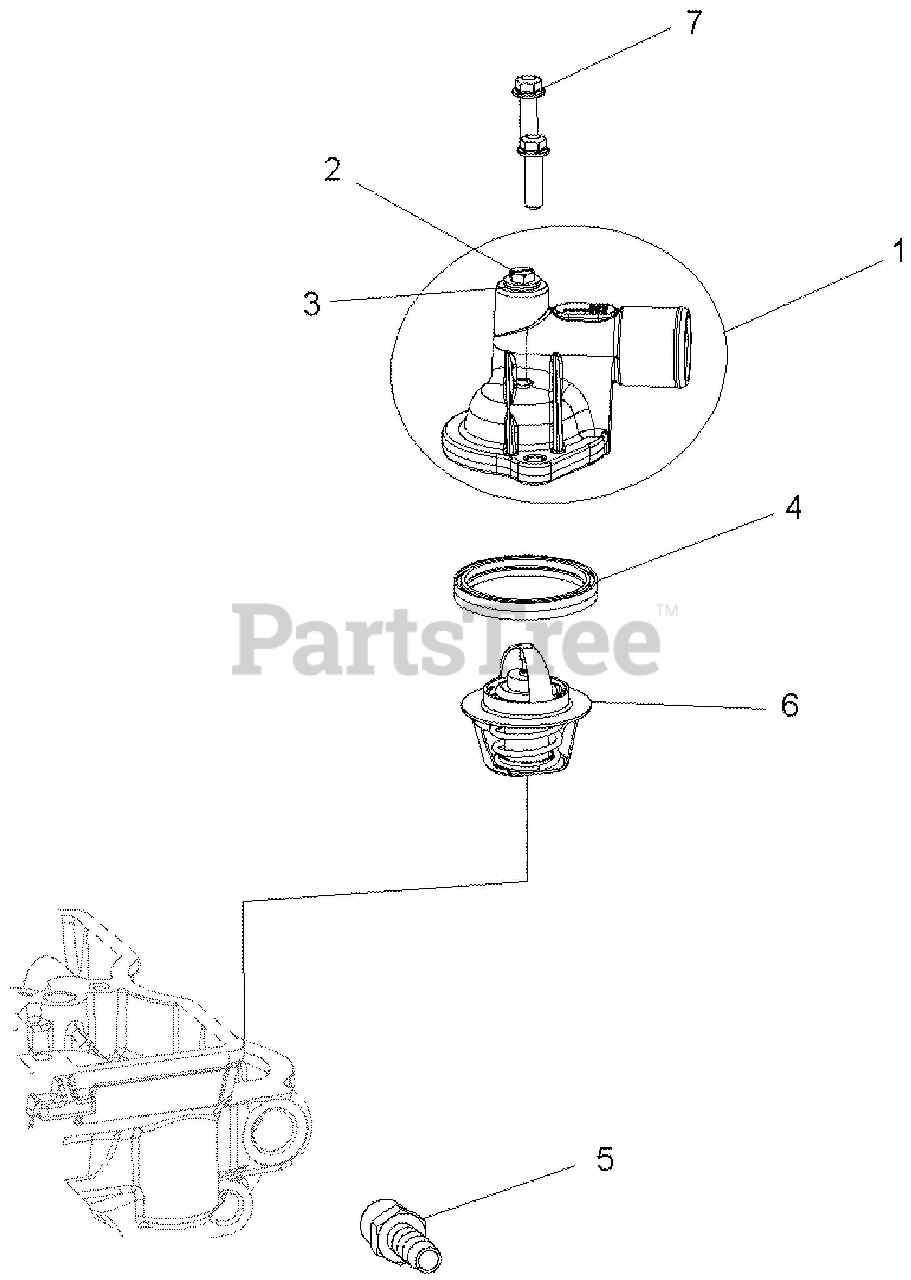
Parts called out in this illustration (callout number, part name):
1	ASM-THERMOSTAT COVER W/BLEED
1	COVER-THERMOSTAT,ANGLED,MACH
2	SCR-M6X1.0X13,SL/HX/FL-Z,BLEED
3	WASHER-FLAT
4	SEAL-THERMOSTAT
5	FITTING-3/8NPTFX1/2 HOSE BARB
6	THERMOSTAT-44M FLANGE,180F
7	SCR-M6X20,HXFLG,0600214
